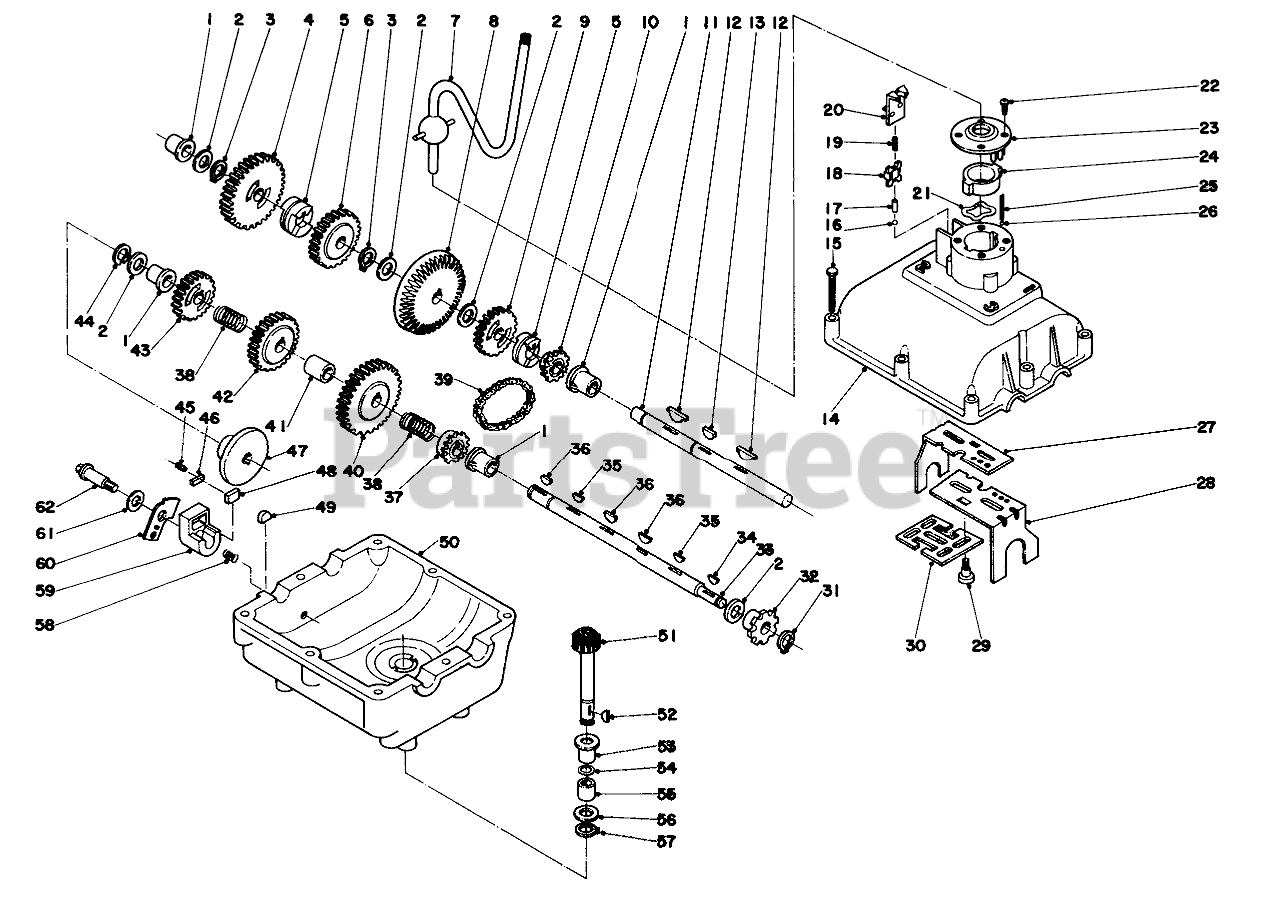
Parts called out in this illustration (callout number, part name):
1	Flange Bearing
2	WASHER KIT
3	Retaining Ring
4	Spur Gear 30T
5	Clutch Collar
6	Spur Gear 25T
7	Shift Lever
8	Bevel Gear 42T
9	Spur Gear 20T
10	Sprocket 12T
11	Drive Shaft
12	Hi Pro Key
13	Woodruff Key
14	Upper Housing
16	Ball Detent
17	Actuating Pin
18	Carrier Contact Assembly
19	Compression Spring
20	Terminal Board
21	Wave Washer
23	Nylon Cover
24	Nylon Insert
25	Detent Spring
26	Detent Ball
27	RH FORK
29	Shoulder Screw
30	Lock-Out Plate
31	Retaining Ring
32	Sprocket 8T
33	Output Shaft
34	Woodruff Key
36	Woodruff Key
37	Sprocket 12T
38	Spring Compression
40	Spur Gear 30T
41	Spacer
42	Spur Gear 25T
43	Spur Gear 20T
44	RETAINING RING
45	Set Screw
46	Spacer
47	BRAKE DISC
48	FRICTION PUCK
49	FRICTION PUCK
50	Lower Housing
51	Input Shaft
52	Woodruff Key
53	Flange Bearing
54	Washer
56	Washer
57	RING-Retaining
58	Compression Spring
59	Brake Jaw
60	Actuating Lever
61	Washer Kit
62	Shoulder Bolt
